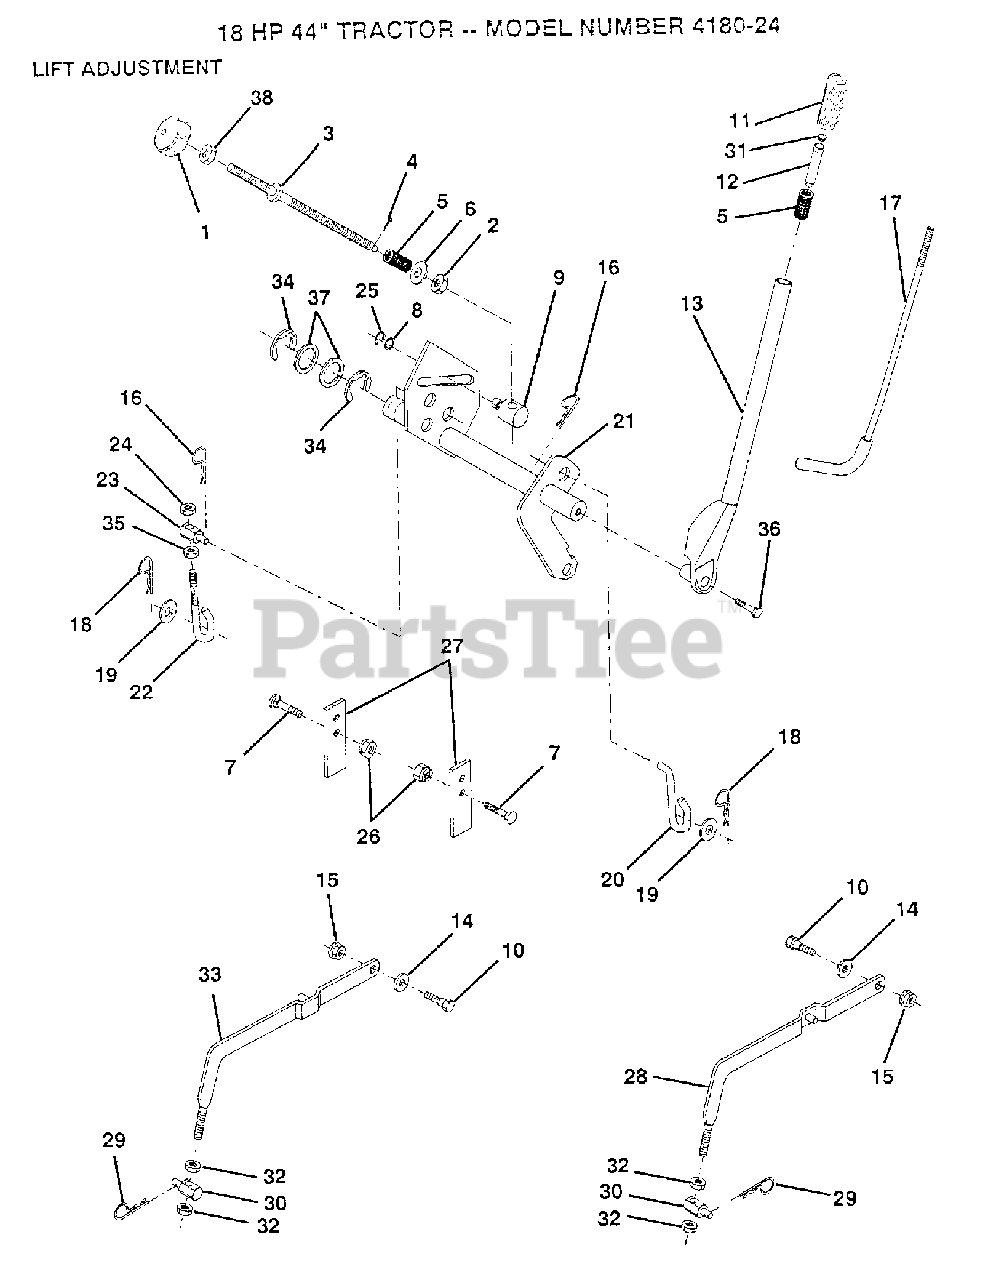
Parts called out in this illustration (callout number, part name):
1	HDLE ADJ LIFT
3	ROD LIFT LT
6	WASHER
8	WASHER
9	TRUNION LT
10	BOLT, SHOULDER LT
11	GRIP
12	PLUNGER BUT KIT
13	LIFT LEVER KIT
14	WASHER T
16	RETAINER SPRING
17	LEVER ROD LT
18	SPRING.RETAINER
19	WASHER T
20	LIFT LINK LT
22	LINK ADJ T
23	TRUNNION T
24	NUT LOCK YTH
25	KLIP RING
26	LOCKNUT
28	RH SUSP ARM ASM
29	SPRING H
31	PLUNGER BUT KIT
33	LH SUSP ARM ASM
36	Hex Bolt
38	NUT
